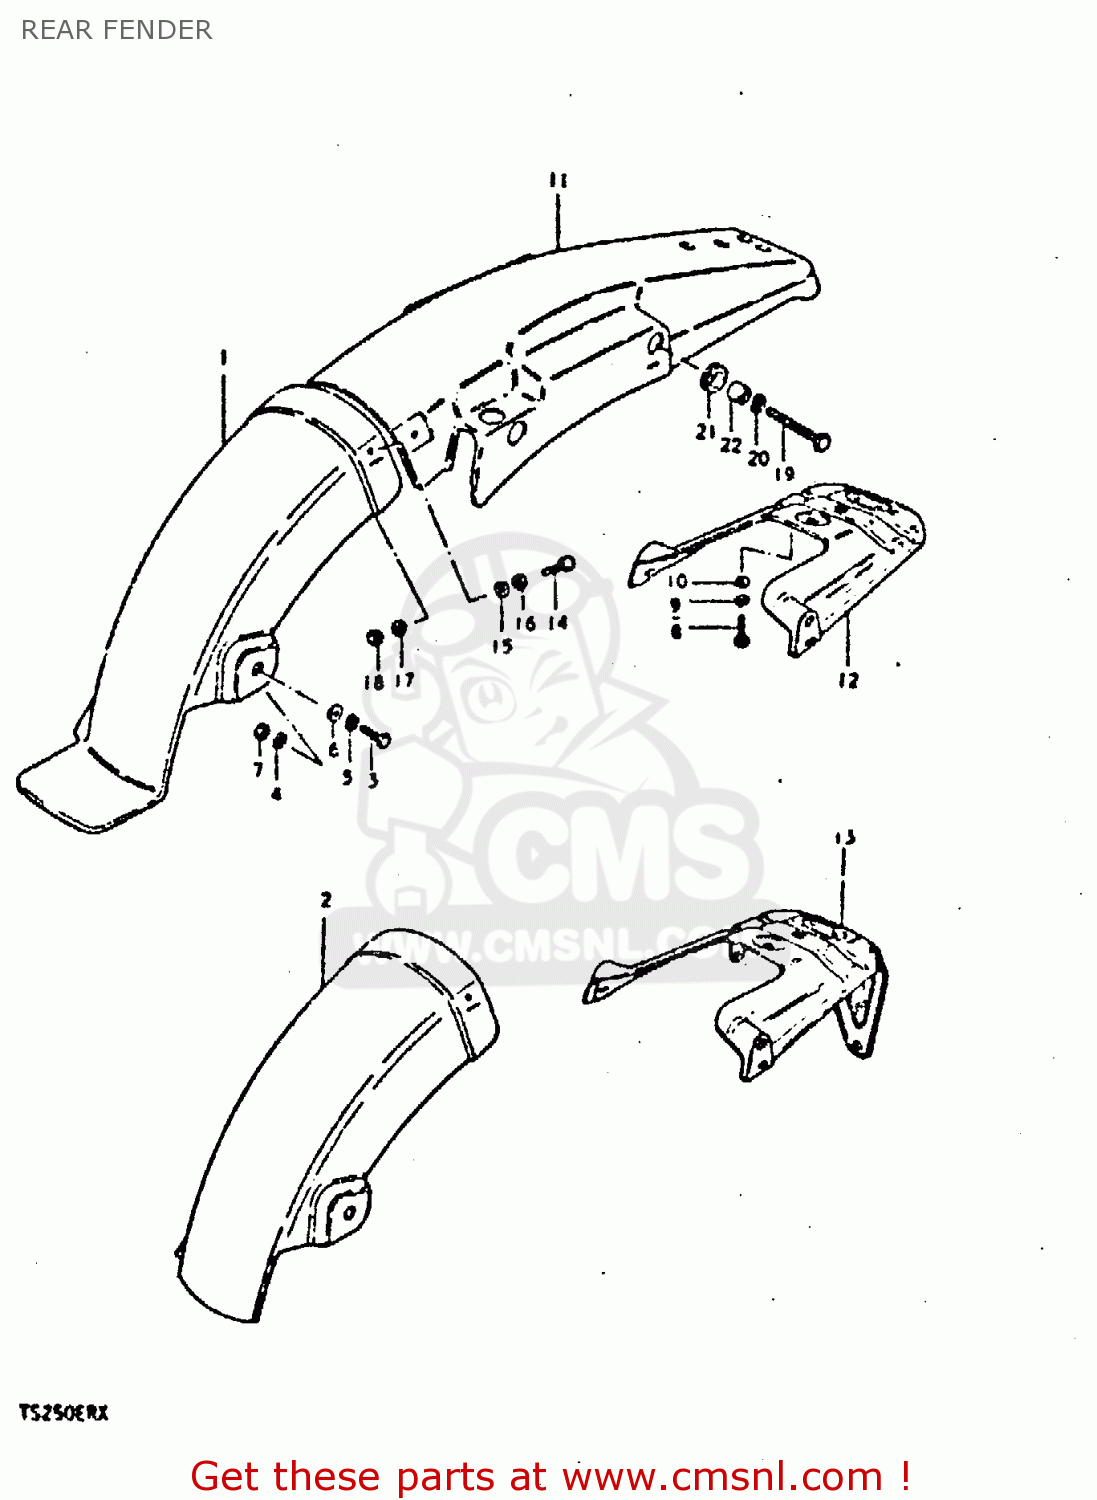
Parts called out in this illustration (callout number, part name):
1	FENDER,REAR
3	BOLT, UPPER
4	WASHER
5	LOCK WASHER
6	WASHER
7	NUT
8	BOLT
9	LOCK WASHER
10	WASHER
11	FENDER, REAR
12	REINFORCEMENT,REAR FENDER
14	BOLT
15	WASHER (5.5X16X1.2)
16	LOCK WASHER
17	WASHER(5.2X16X1)
18	NUT
19	BOLT (8X30)
20	LOCK WASHER
21	CUSHION
22	SPACER (8.2X12X7.5)
